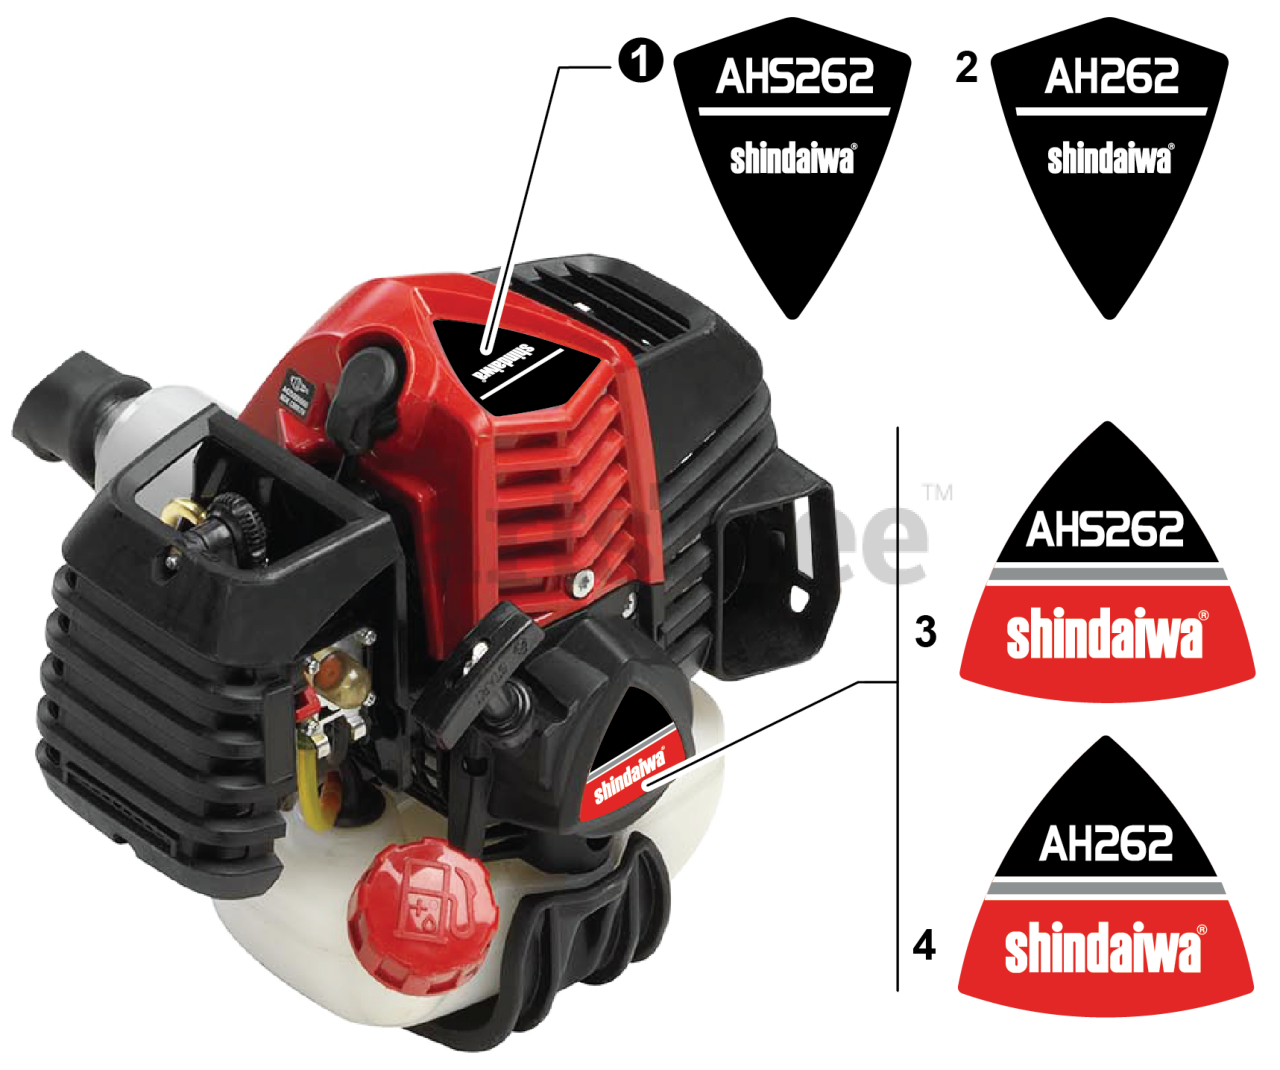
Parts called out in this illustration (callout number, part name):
1	LABEL - MODEL AHS262
2	LABEL - MODEL AH262
3	LABEL - RECOIL STARTER - AHS262
4	LABEL - RECOIL STARTER - AH262
